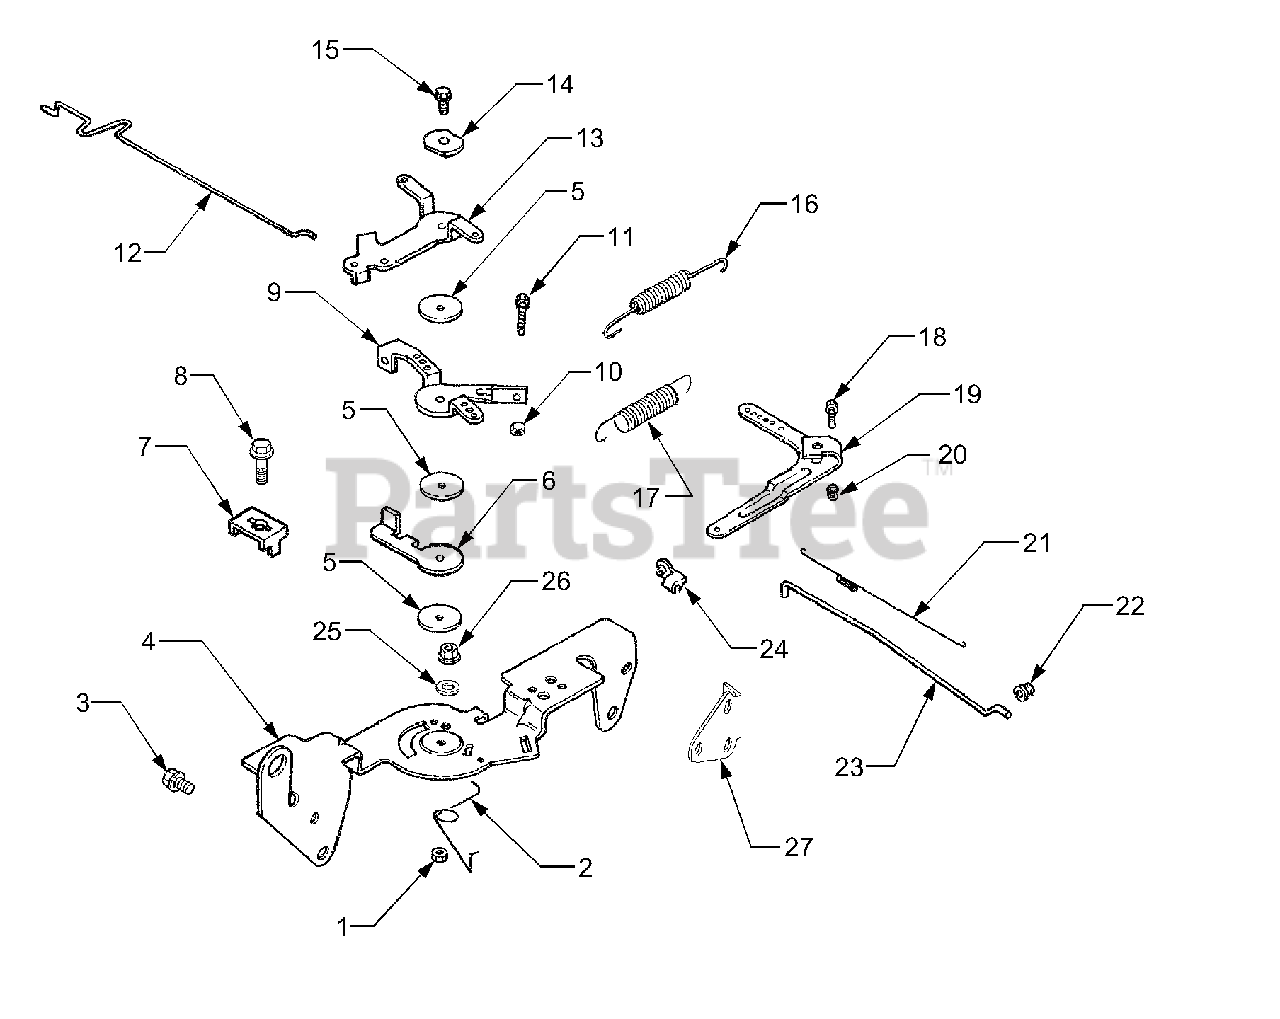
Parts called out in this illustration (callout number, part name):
1	Nut, Hex Lock M5 x 0.8
2	Spring, Choke Return
3	Screw, Hex Flange M6 x 1.0 x 16
4	Bracket, Control
5	Washer , Plain 5.5mm
6	Lever, Throttle Actuator
7	Clamp, Cable
8	Screw, Hex Flange M5 x 0.8 x 16
9	Lever, Throttle Control
10	Nut, Hex M4 x 0.7
11	Screw, Hex Cap M4 x 0.7 x30
12	Linkage, Choke
13	Lever, Choke
14	Washer, Spring 1/4"
15	Screw, Hex Flange M5 x 0,.8 x 20
16	Spring, Throttle Limiter
17	Spring, Governor
18	Screw, Round Hd. Square Neck
19	Lever, Governor
20	Nut, Hex Flange M6 x 1.0
21	Spring, Linkage
22	Bushing, Linkage Retaining
23	Linkage, Throttle
24	Bushing, Linkage Retaining
27	Bracket, Support
